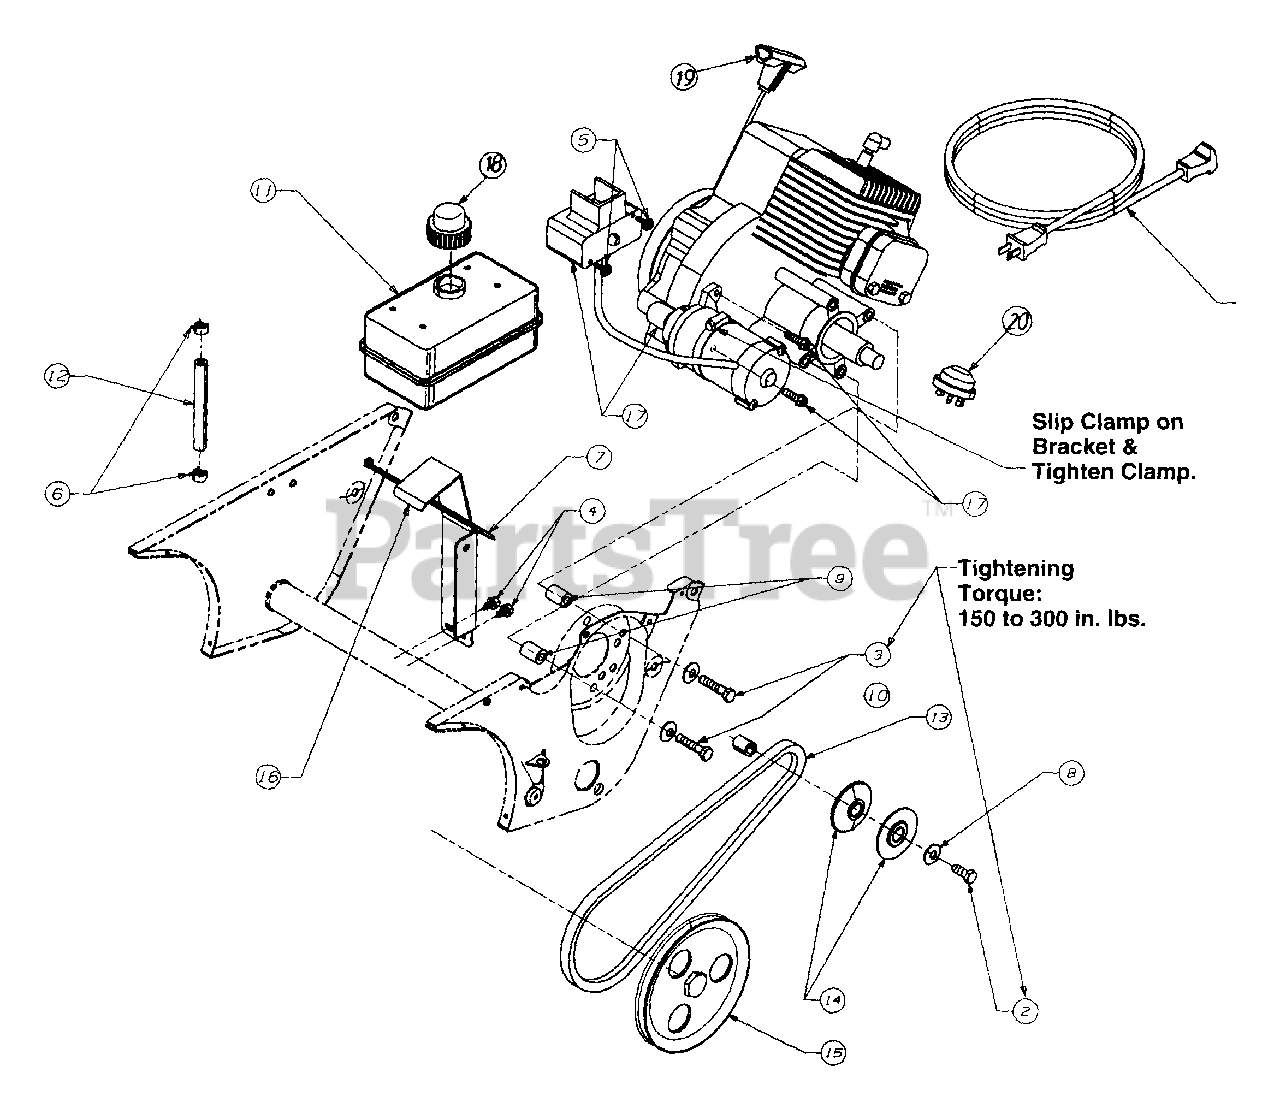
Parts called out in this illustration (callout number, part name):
1	Cord, Extension 120V (E142 Only)
2	Screw, Hex Cap
3	Screw, Hex Cap
4	Screw, Hex Washer
5	Screw, Hex Self-Tapping (E142 Only)
6	Hose Clamp
7	Cable Tie
8	Washer, Bell
9	Spacer
10	Spacer
11	Tank, Gas 1 Qt.
12	Hose, Fuel Line .25 x 6"
13	V - Belt
14	V - Pulley Half
15	Pulley
18	Gas Cap
19	Handle, Recoil
